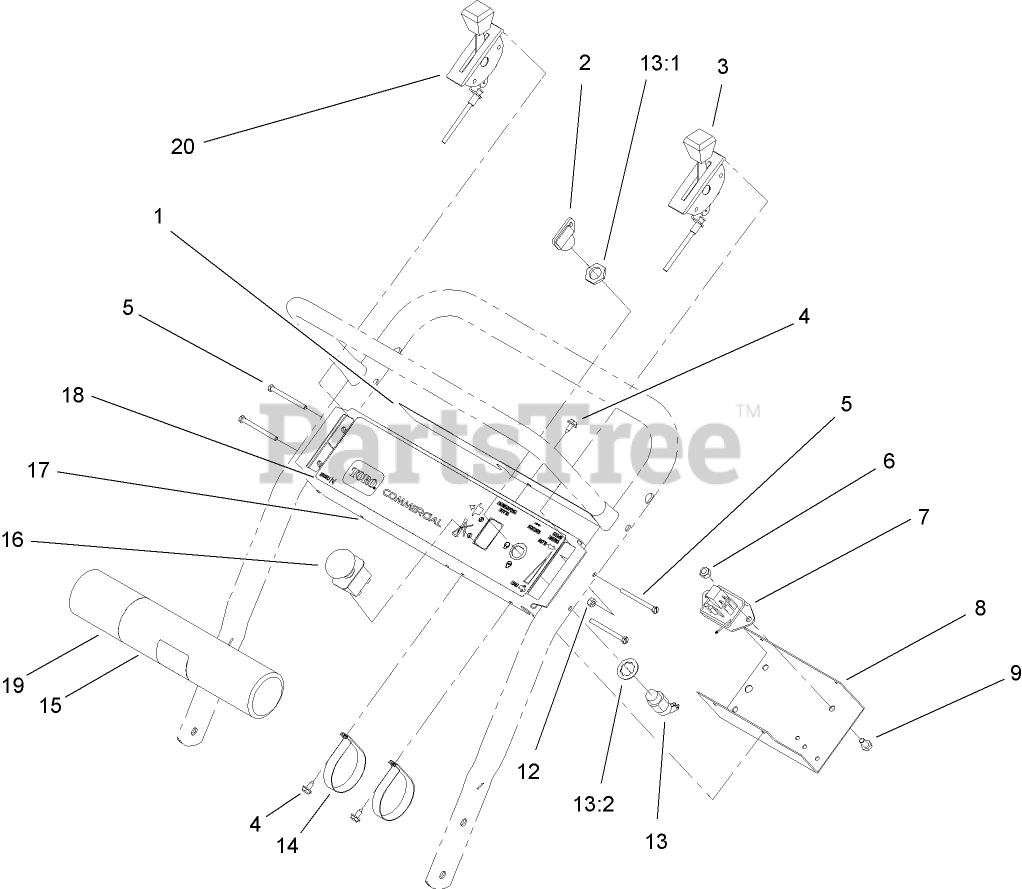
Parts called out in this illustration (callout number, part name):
1	DECAL-DANGER
2	KEY-IGNITION
3	CABLE-THROTTLE
4	SCREW-HWHTF
5	SCREW-SHH
6	NUT-LOCK, NI
7	MODULE-DELAY
8	PANEL-BOTTOM
9	SCREW-HH
12	NUT-LOCK, NI
13	SWITCH-ON / OFF
13:1	NUT-HH
13:2	WASHER-TOOTH, INTERNAL
14	CLAMP-R
15	TUBE-MANUAL
16	SWITCH-PTO
17	PANEL-CONTROL
18	DECAL-PANEL, CONTROL
19	CAP-HOUSING
20	CABLE-CHOKE
